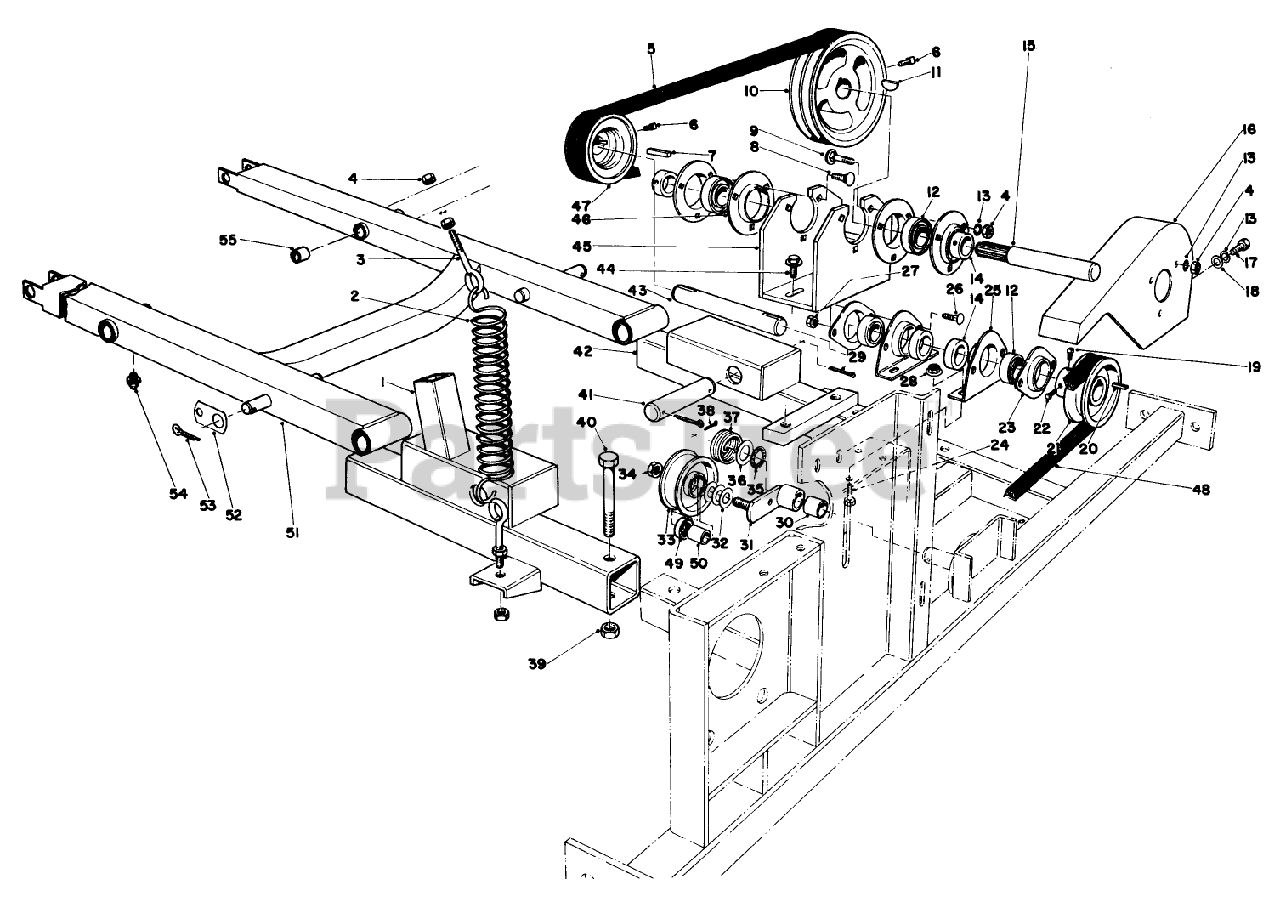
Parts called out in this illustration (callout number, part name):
4	NUT-HEX
6	SCREW-SET, SQH
8	SCREW-CARR
9	BOLT-CARR
11	KEY-WOODRUFF
12	BEARING
13	WASHER-LOCK/SP
14	COLLAR-LOCK, BEARING
15	JACKSHAFT
17	SCREW-HH
18	WASHER-PLAIN
19	SCREW-SQH
22	SCREW-SQH
24	SCREW-HH
25	FLANGE
26	BOLT-CARR
27	NUT-HF
28	NUT-HHF, WHIZ
29	3/32 X 1-3/4 LG COTTER
31	Idler Arm (Incl. Ref. #30)
32	WASHER-FLAT
38	PIN-COTTER
39	NUT-LOCK, CONE
40	SCREW-HH
44	SCREW-HHF
51	LIFT ARM WA
53	PIN-COTTER
55	7/8 ID X 1.128 X 7/8 LG BSHG
